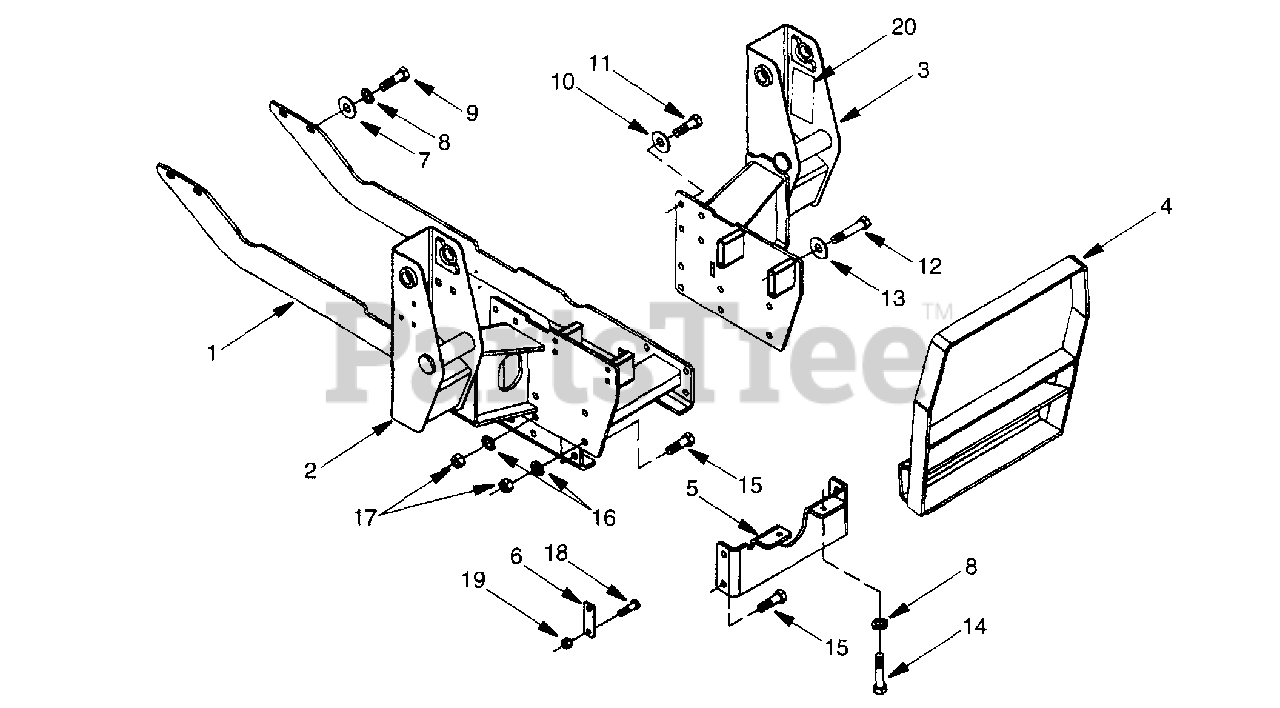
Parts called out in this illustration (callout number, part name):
1	Rear Axle Mount
2	Loader Mount, RH
3	Loader Mount, LH
4	Grille Guard
5	Front Mounting Plate
6	Valve Bracket
7	1/2 Flat Washer, Hardened
8	1/2 Lock Washer
9	12mm x 1.75 x 110, Cap Scrw, CL 8.8
10	Washer.566 x 1.25 x .134 HT
11	14mm x 2 x 35 Cap Screw, CL 8.8
12	12mm x 1.25 x 110 Cap Scrw, CL 8.8
13	Washer, .488 x 1.25 x .134 HT
14	12mm x 1.25 x 110 Cap Scrw, CL 8.8
15	5/8 NC x 1.5, HHCA, GR5
16	5/8 Lock Washer
17	5/8 NC Plated Hex Nut
18	3/8 NC x 1 HHCS, GR5
19	3/8 NC Lock Nut
20	Mounting/Removal Instruction Decal
